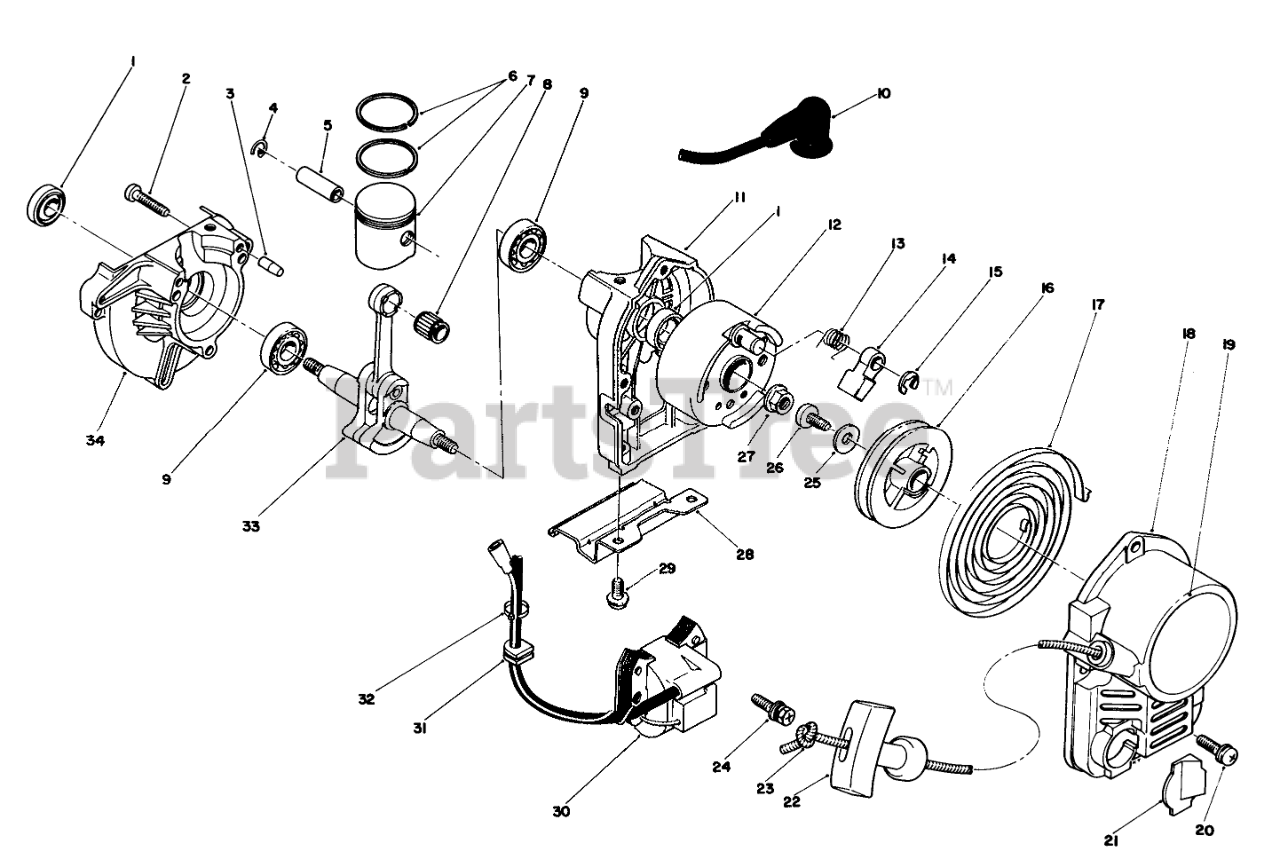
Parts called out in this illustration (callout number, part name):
1	OIL SEAL
2	Screw
4	PISTON PIN CLIP
5	Pin-Piston
6	TOP RING
7	Piston
8	NEEDLE BEARING
9	BEARING
10	CAP-PLUG
11	STARTER CASE
12	Rotor
13	Spring-Return
14	RATCHET
15	SNAP RING
17	SPRING
18	Case-Starter
19	RECOIL COVER DECAL
20	SCREW & WASHER
21	Grommet
22	Knob-Starter
23	Rope-Recoil
24	Bolt & Washer
25	Washer
26	SCREW
28	STAND
29	SCREW & WASHER
30	IGNITION COIL
31	GROMMET
33	CRANKSHAFT ASM
34	DRIVE CASE
